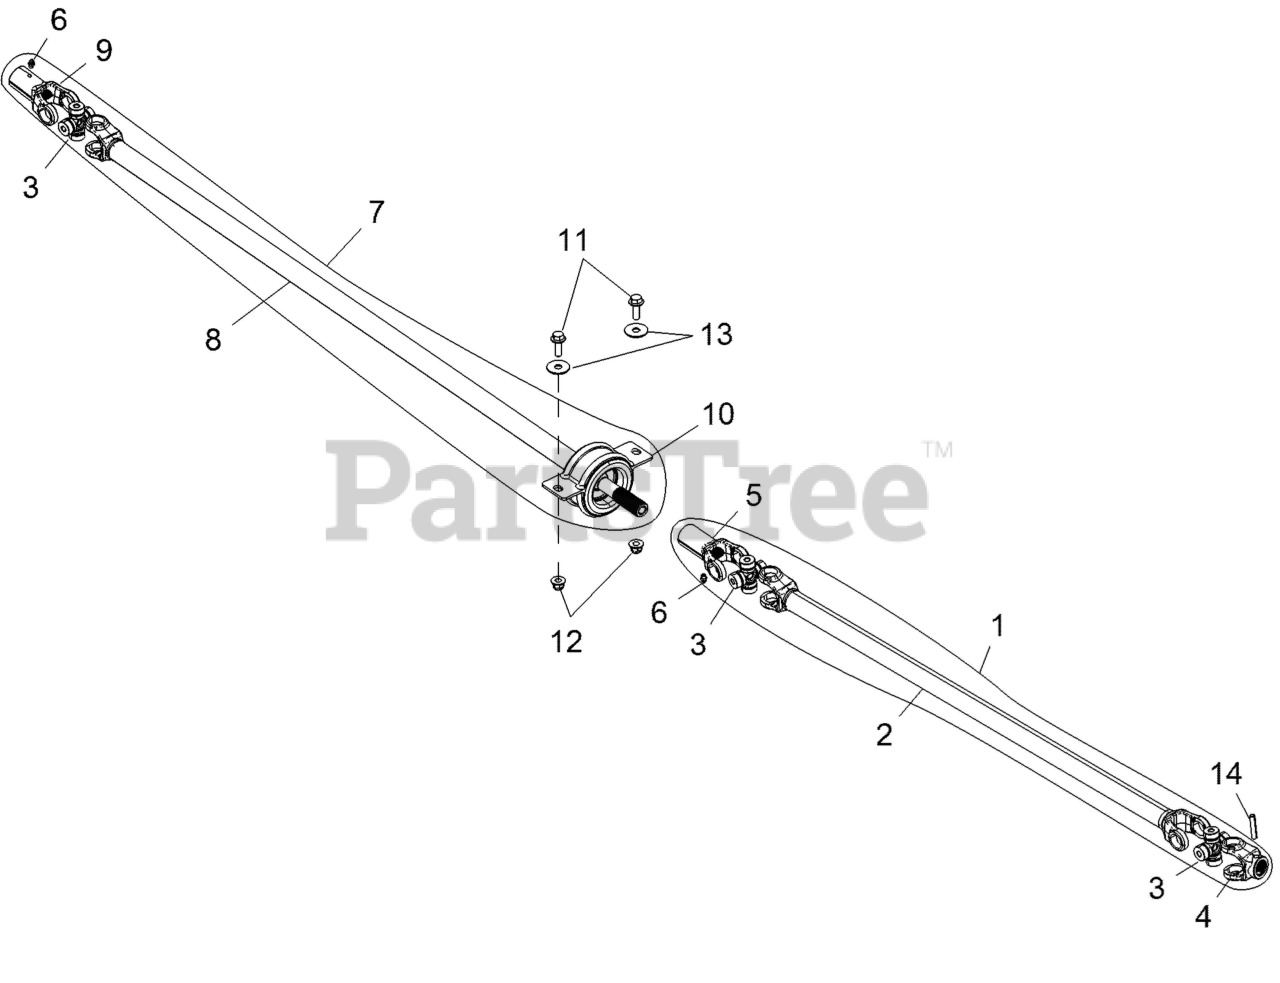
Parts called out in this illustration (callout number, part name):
1	ASM-PROPSHAFT,FRONT
2	WELD-PROPSHAFT,FRONT
3	U-JOINT-1000 SERIES
4	YOKE-PIN
5	YOKE, SLIP, INDEXED
6	FITTING, LUBRICATION
7	ASM-PROPSHAFT,REAR
8	WELD-PROPSHAFT,REAR
9	YOKE-SLIP
10	ASM, FLEX BEARING
11	SCR-HXFL-M10X1.25X30 8.8 ZOD
12	NUT-M10X1.25,FLG,NYLOC-OLIVE D
13	WASHER, FLAT
14	PIN,SPRING(10)
